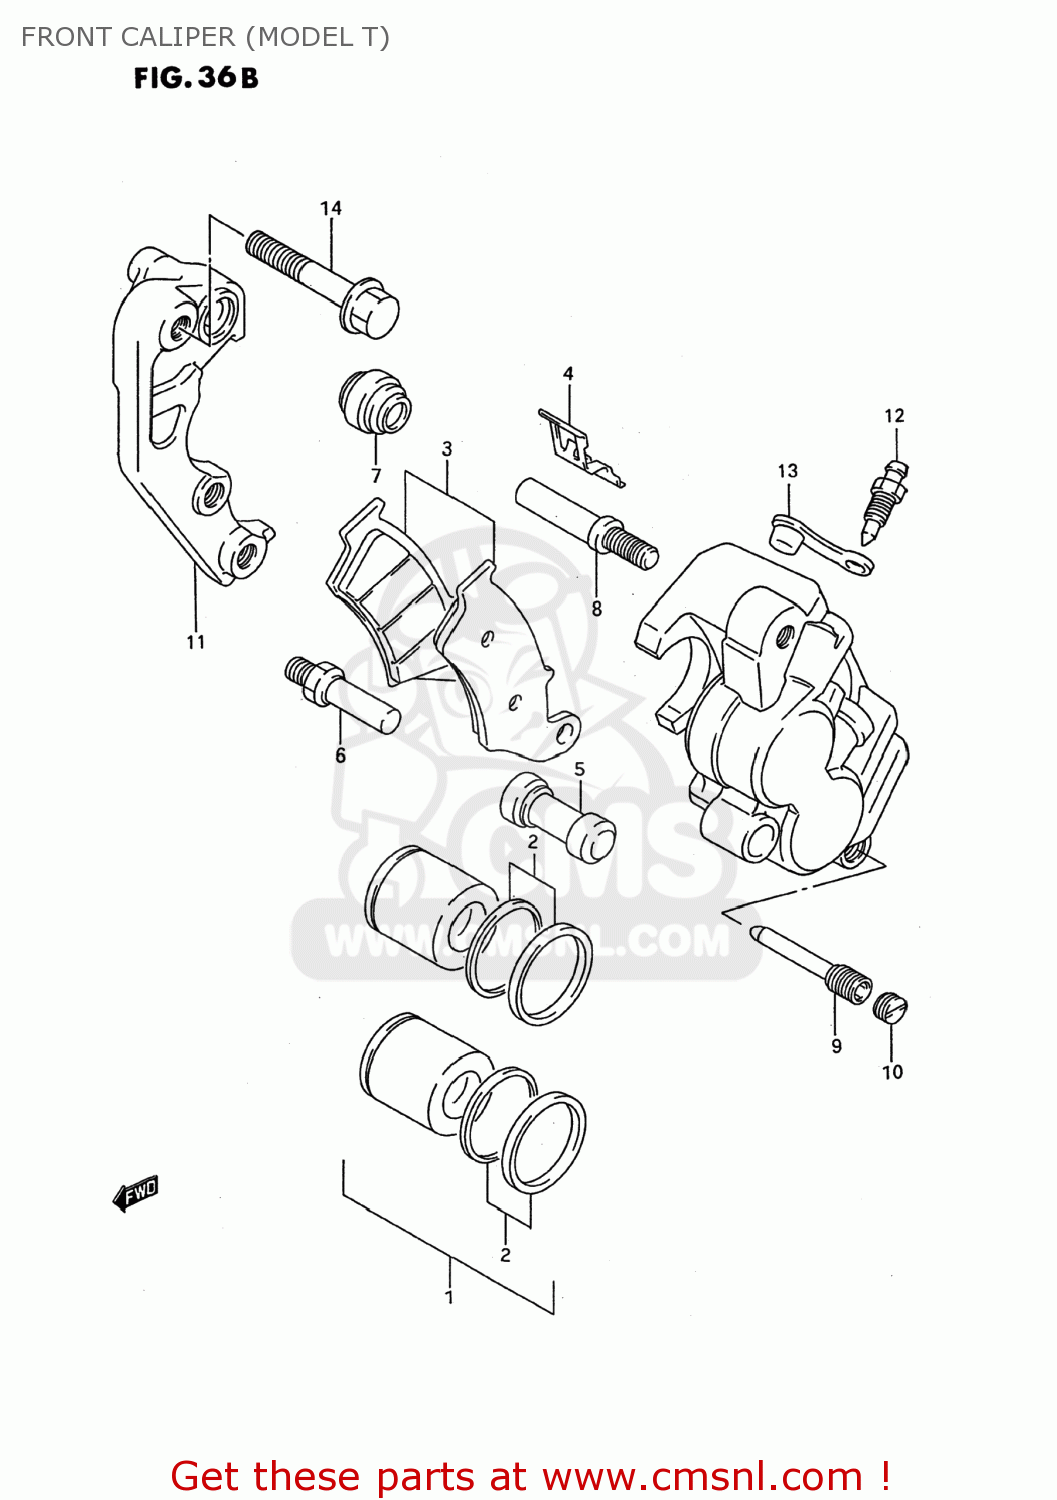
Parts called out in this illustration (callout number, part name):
1	PISTON SET
2	SEAL SET,PISTON
3	PAD SET (NAS)
4	SPRING,PAD
5	BOOT
6	PIN,BOLT
7	BOOT
8	PIN
9	PIN,HANGER
10	PLUG,PIN
11	BRACKET
12	BLEEDER
13	CAP,BLEEDER
14	BOLT(8X40)
